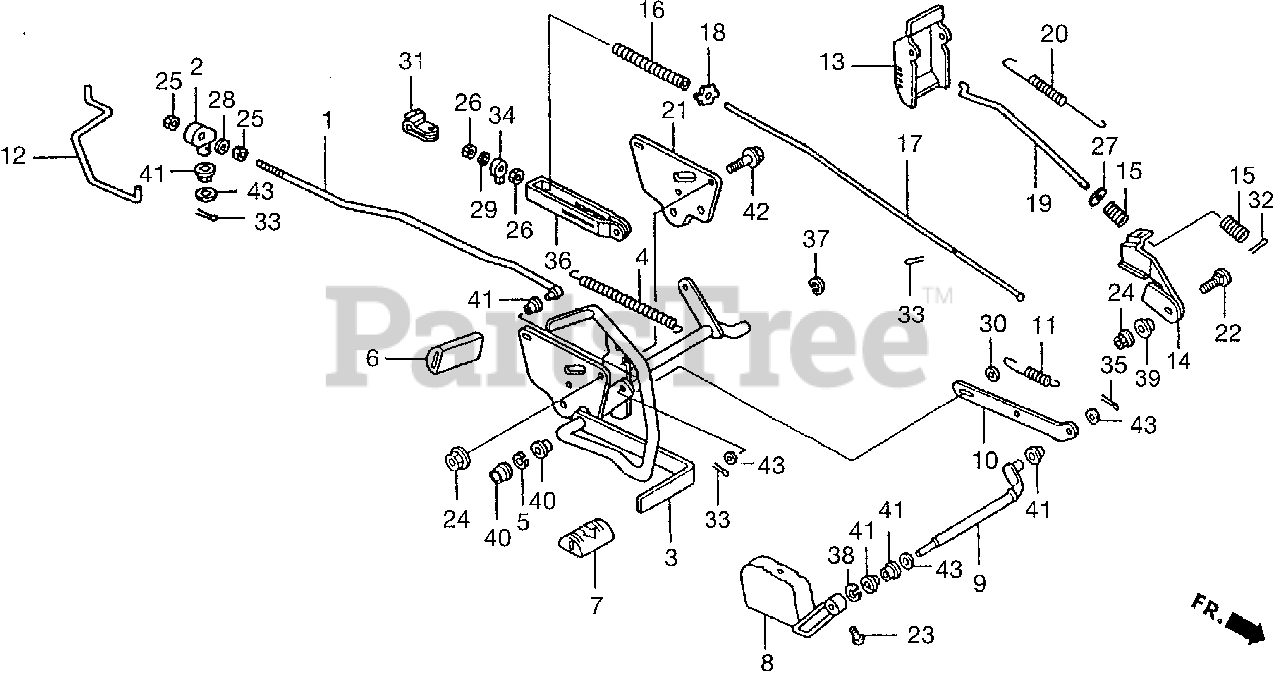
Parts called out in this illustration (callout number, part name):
1	ROD, GEARSHIFT
3	PEDAL, COMBO BRAKE/FORWARD
4	SPRING, BRAKE PEDAL
5	COLLAR, PEDAL
6	RUBBER, BRAKE PEDAL
7	RUBBER, FORWARD PEDAL
8	PEDAL, REVERSE
9	SHAFT, REVERSE
10	LINK, REVERSE
11	SPRING, REVERSE
12	LEVER, NEUTRAL VALVE
13	LEVER, PARKING BRAKE
14	ARM, PARKING BRAKE
15	SPRING, PUSH ROD
16	SPRING, BRAKE LOAD SETTING
17	ROD, FOOT BRAKE
18	GUIDE, BRAKE ROD
19	ROD, PARKING BRAKE
20	SPRING, PARKING BRAKE RETURN
21	PLATE, BRAKE
22	BOLT, CARRIAGE (8X20)
23	SCREW, REVERSE PEDAL SETTING
24	NUT, FLANGE (8MM)
25	NUT, HEX. (12MM)
26	NUT, HEX. (10MM)
27	WASHER (6.4X18X1.6)
28	WASHER, LOCK (INNER) (1/2")
29	WASHER, LOCK (INNER) (3/8")
30	WASHER, REVERSE LINK
31	CLIP, R. ROD MOUNTING
32	PIN, COTTER (2X16)
33	PIN, COTTER (2.5X20)
34	PIN, CONTROL LINK
35	PIN, COTTER (3.2X20)
36	RETAINER, BRAKE SPRING
37	RING, CONTROL SNAP
38	RING, HEIGHT ADJUST PIN
39	BUSHING, PARKING BRAKE
40	BUSHING, FLANGED
41	BUSHING, CONTROL
42	BOLT, FLANGE (8X16) (19M7867)
43	WASHER, PEDAL ARM
